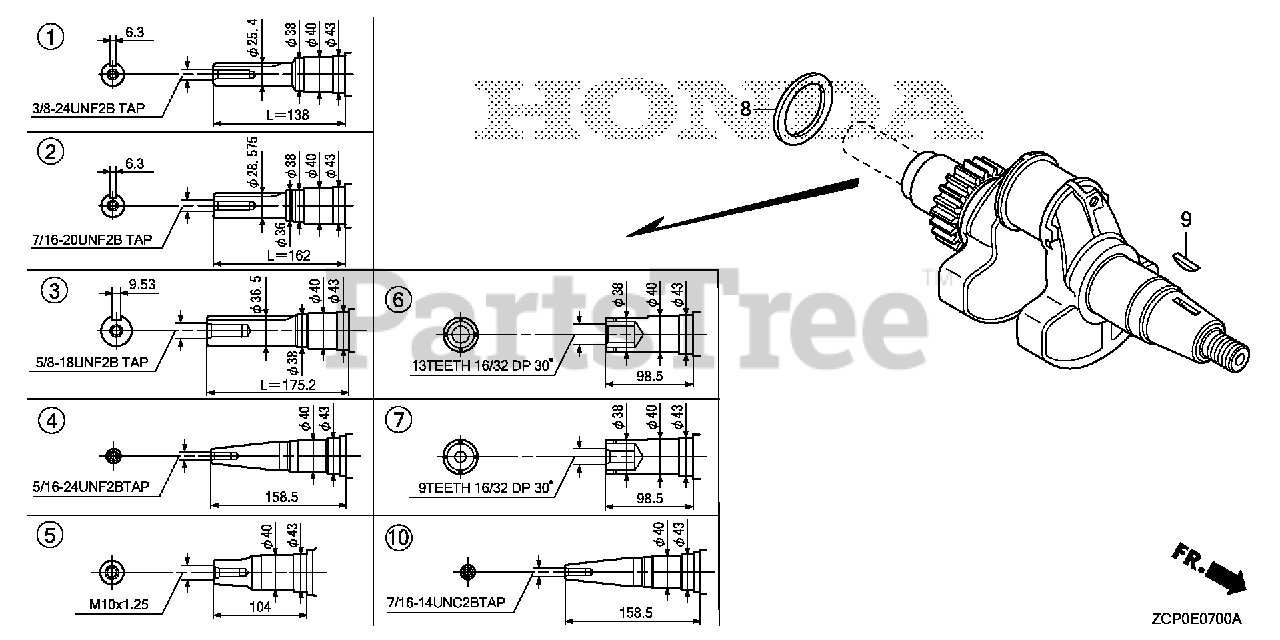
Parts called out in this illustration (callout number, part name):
3	CRANKSHAFT (L=175.2)
8	WASHER, CRANKSHAFT THRUST
9	KEY, SPECIAL WOODRUFF (25X18)
